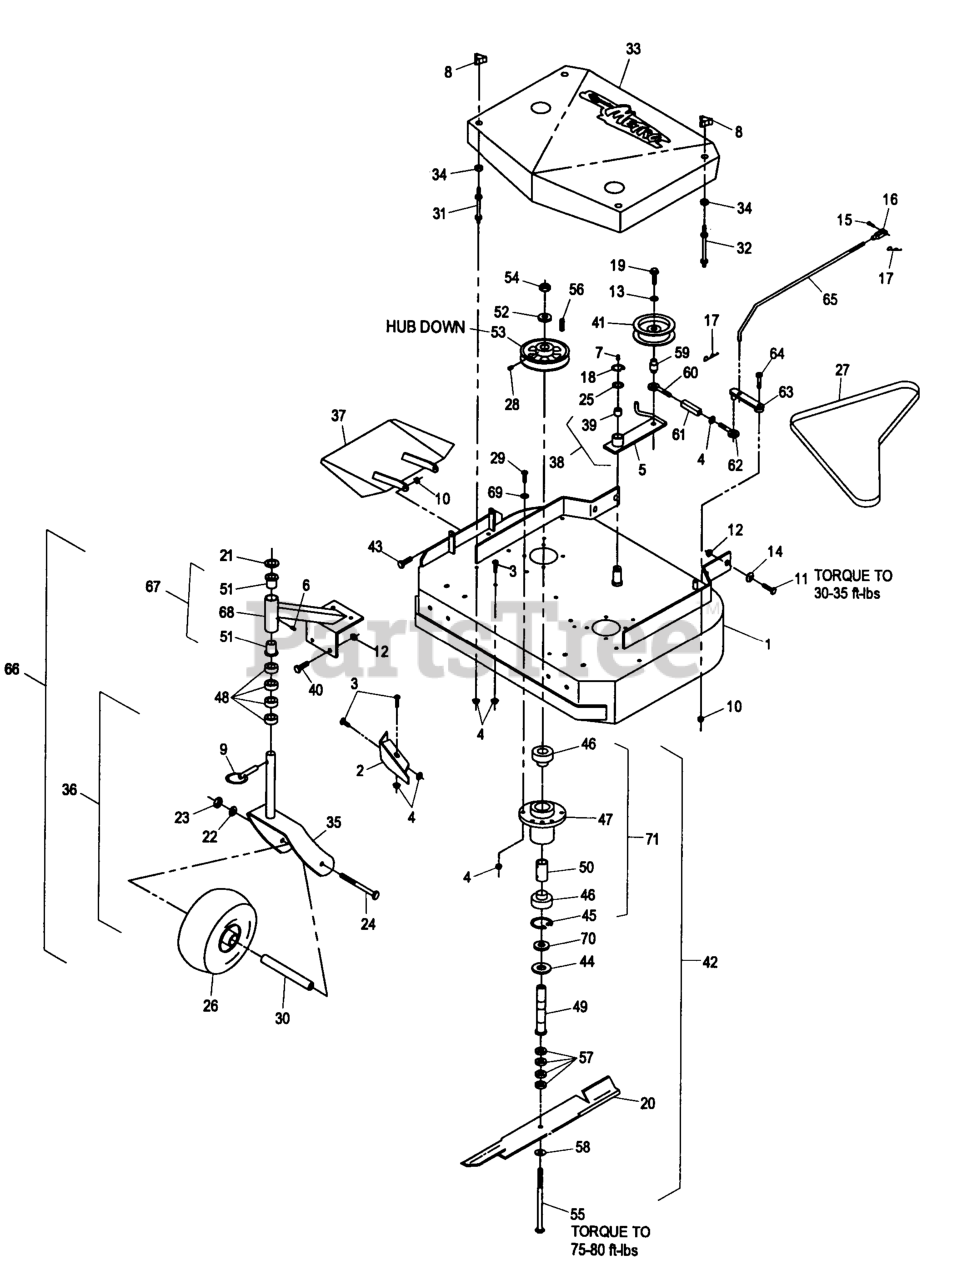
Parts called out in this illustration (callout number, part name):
2	BAFFLE-DOGLEG
8	KNOB-3 PRONG
15	PIN-CLEVIS
16	YOKE-ADJUSTABLE
17	PIN-COTTER
21	WASHER-FLAT
25	WASHER-SPINDLE
27	BELT,BLADE DRIVE
28	SCREW-SET
31	STUD-SHIELD, BELT (SHORT)
32	STUD-SHIELD, BELT (LONG)
37	Chute
39	BEARING,POWDERED METAL
42	HOUSING,CUTTER COMPLETE(S
44	GUARD-BEARING, BOTTOM
46	BEARING
48	SPACER-CASTER
49	TUBE-SPINDLE, SHORT
50	SPACER-BEARING
51	BEARING-FLANGED
52	WASHER-RETAINER, SHEAVE
55	SCREW-CAP, HH
58	WASHER-SPRING
59	BUSHING-ENGAGEMENT
60	EYEBOLT-THREAD, LH
61	BODY-TURNBUCKLE
62	EYEBOLT-THREAD, RH
64	BOLT,SHLDR KSKH
65	ARM-ASSIST, LINKAGE
66	CASTER/MOUNT ASM
67	SUPPORT ASM
69	WASHER-SPRING
70	SPACER-PULLEY/BEARING
